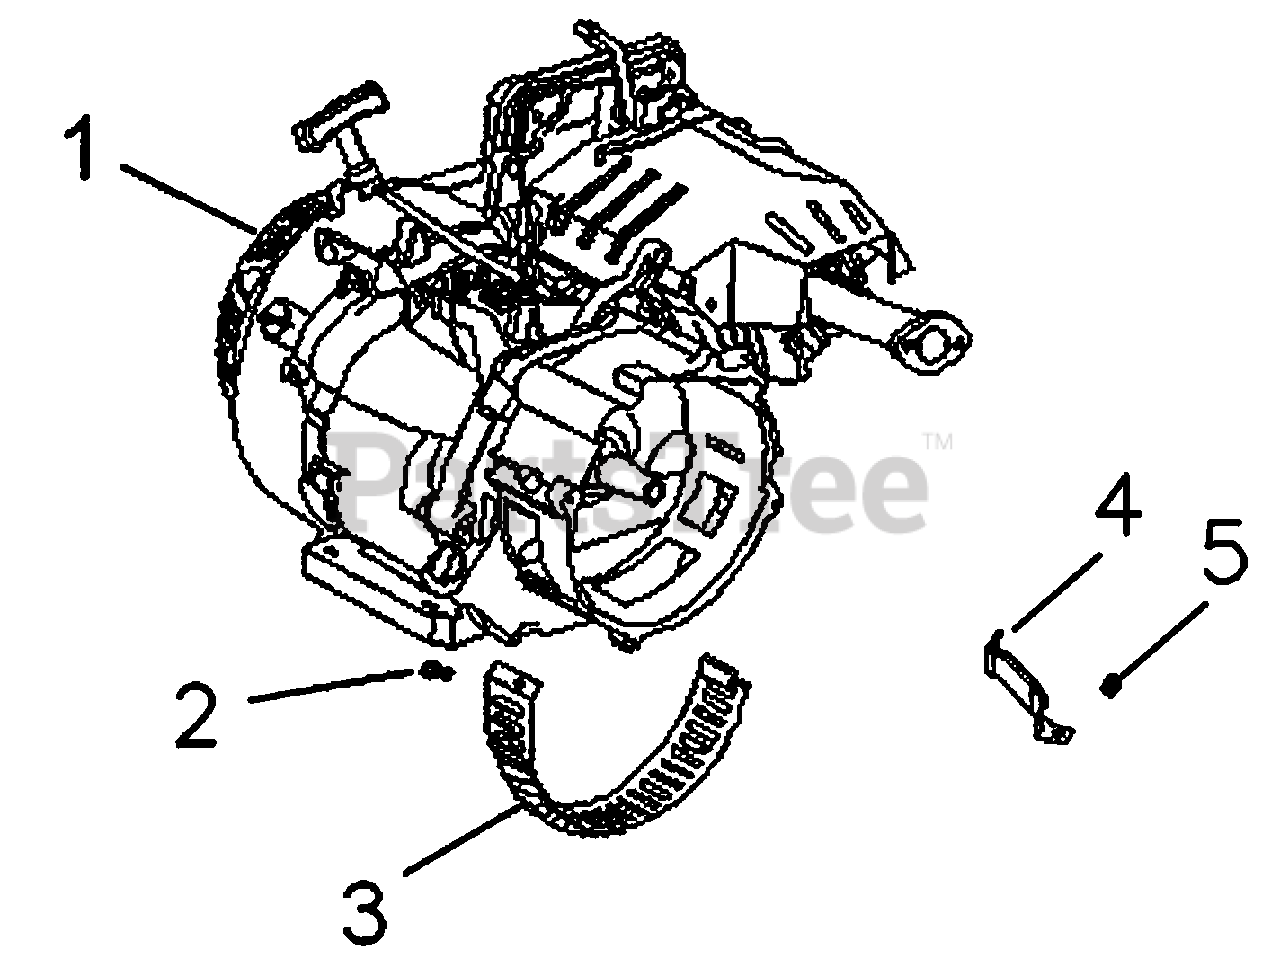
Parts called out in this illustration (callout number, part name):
1	ENGINE G390FA
2	BOLT, FLANGE M5x10
3	ALTERNATOR SCROLL GP
4	BRACKET,AIR CLEANER
5	NUT, FLANGE M6
